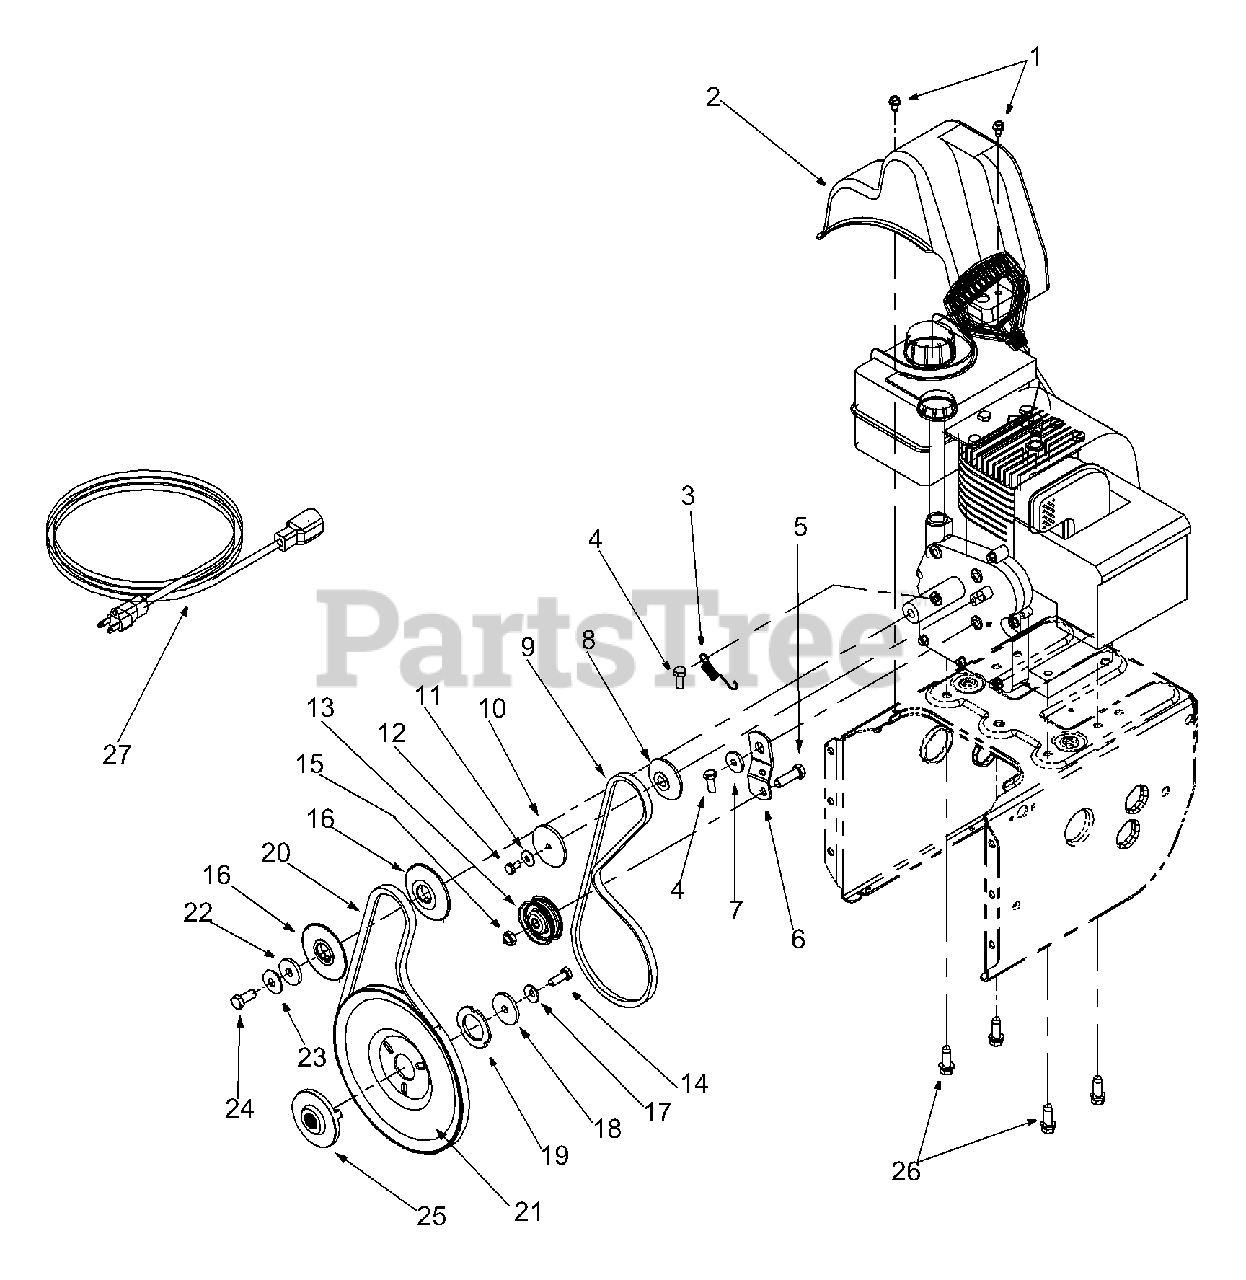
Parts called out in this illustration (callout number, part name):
1	Hex Washer Screw 1/4-20 x .5
2	Belt Cover
3	Extension Spring
4	Hex Screw 5/16-24 x .75
5	Hex Cap Screw 3/8-16 x 1.25
8	Pulley Half
9	V-Belt
10	Pulley Half
11	Bell Washer
12	Hex Cap Screw 1/4-28 x .50
13	Flat Idler
14	Lock Cap Screw 5/16-24
15	Lock Jam Nut 3/8-16
16	Pulley Half
17	Bell Washer
18	Flat Washer
19	Washer
20	Belt
21	Auger Pulley
22	Flat Washer
23	Bell Washer
24	Hex Cap Screw 3/8-24
25	Pulley
26	Hex Washer Screw 3/8-16 x 1.0
27	Extension Cord
